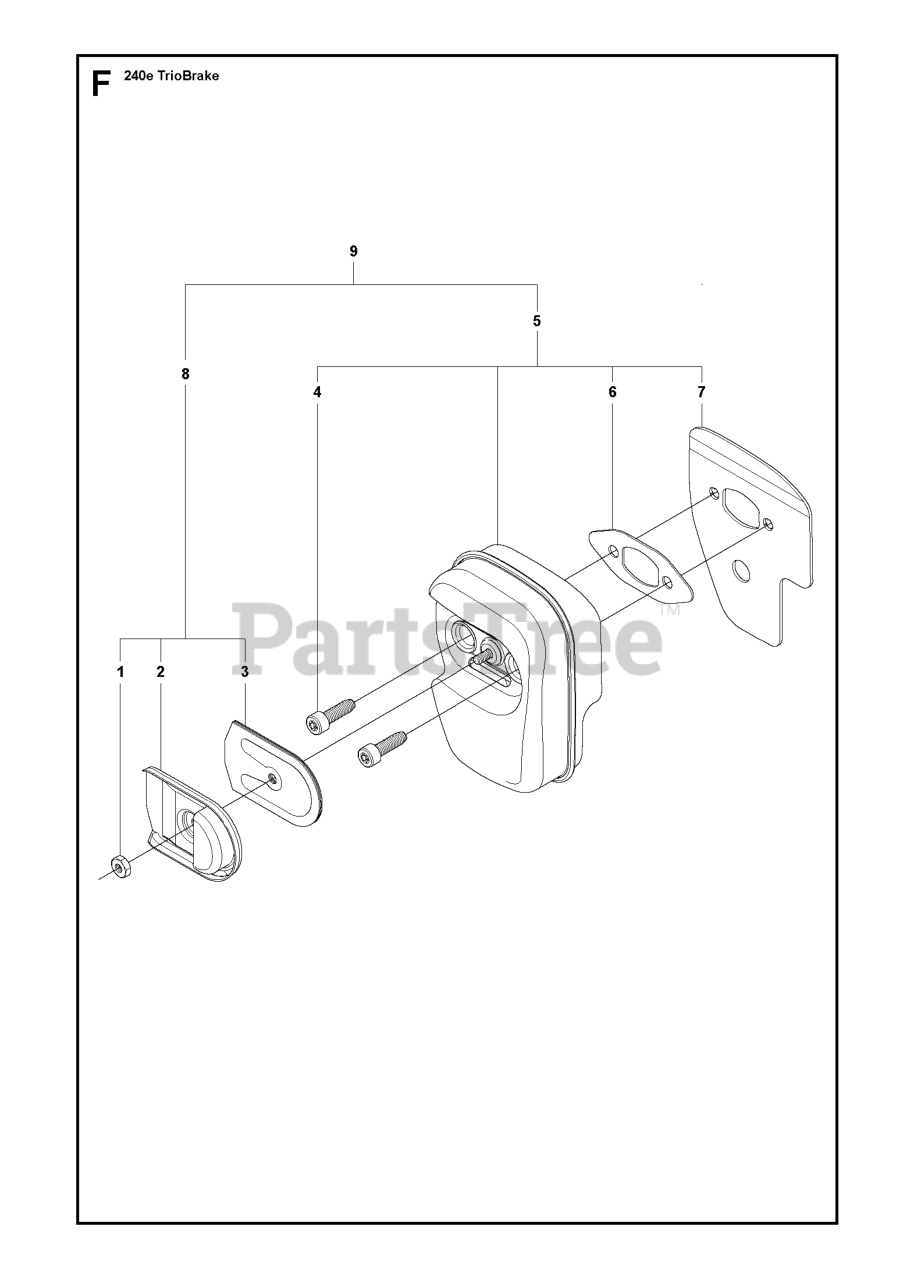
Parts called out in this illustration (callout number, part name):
1	NUT 10MM BRASS
2	EXHAUST PLATE
3	SCREEN ARRESTOR
4	IGNITION MODULE
5	MUFFLER ASSY
8	KIT SPARK ARRESTOR
9	MUFFLER KIT
